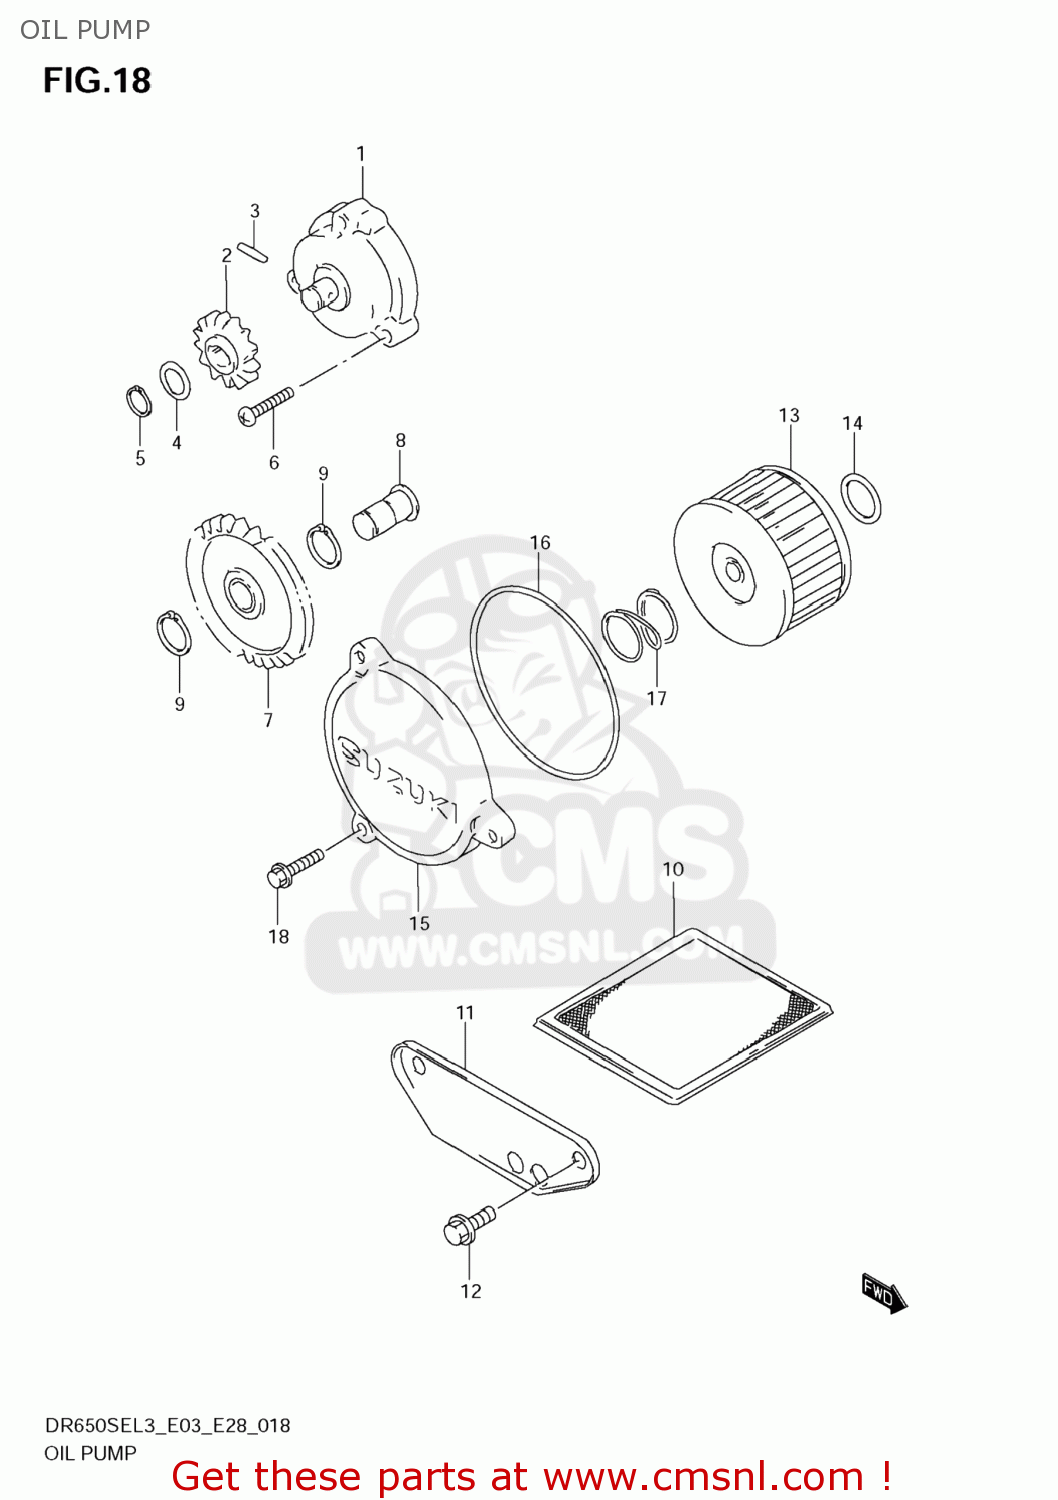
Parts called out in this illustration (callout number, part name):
1	PUMP ASSY,ENGINE OIL
2	GEAR,ENG OIL PUMP DRIVEN
3	PIN(4X15.8)
4	SHIM(10X20X0.5)
5	CIRCLIP
6	SCREW
7	GEAR,OIL PUMP DRIVE(NT:30)
8	SHIFT,ENG OIL PUMP DRIVE GEAR
9	CIRCLIP
10	STRAINER,ENGINE OIL
11	CAP,OIL STRAINER
12	BOLT(6X12)
13	FILTER ASSY,ENGINE OIL
14	O RING(D:2.4,ID:15.8)
15	CAP,OIL FILTER
16	O RING(D:2.4,ID:73)
17	SPRING
18	BOLT
